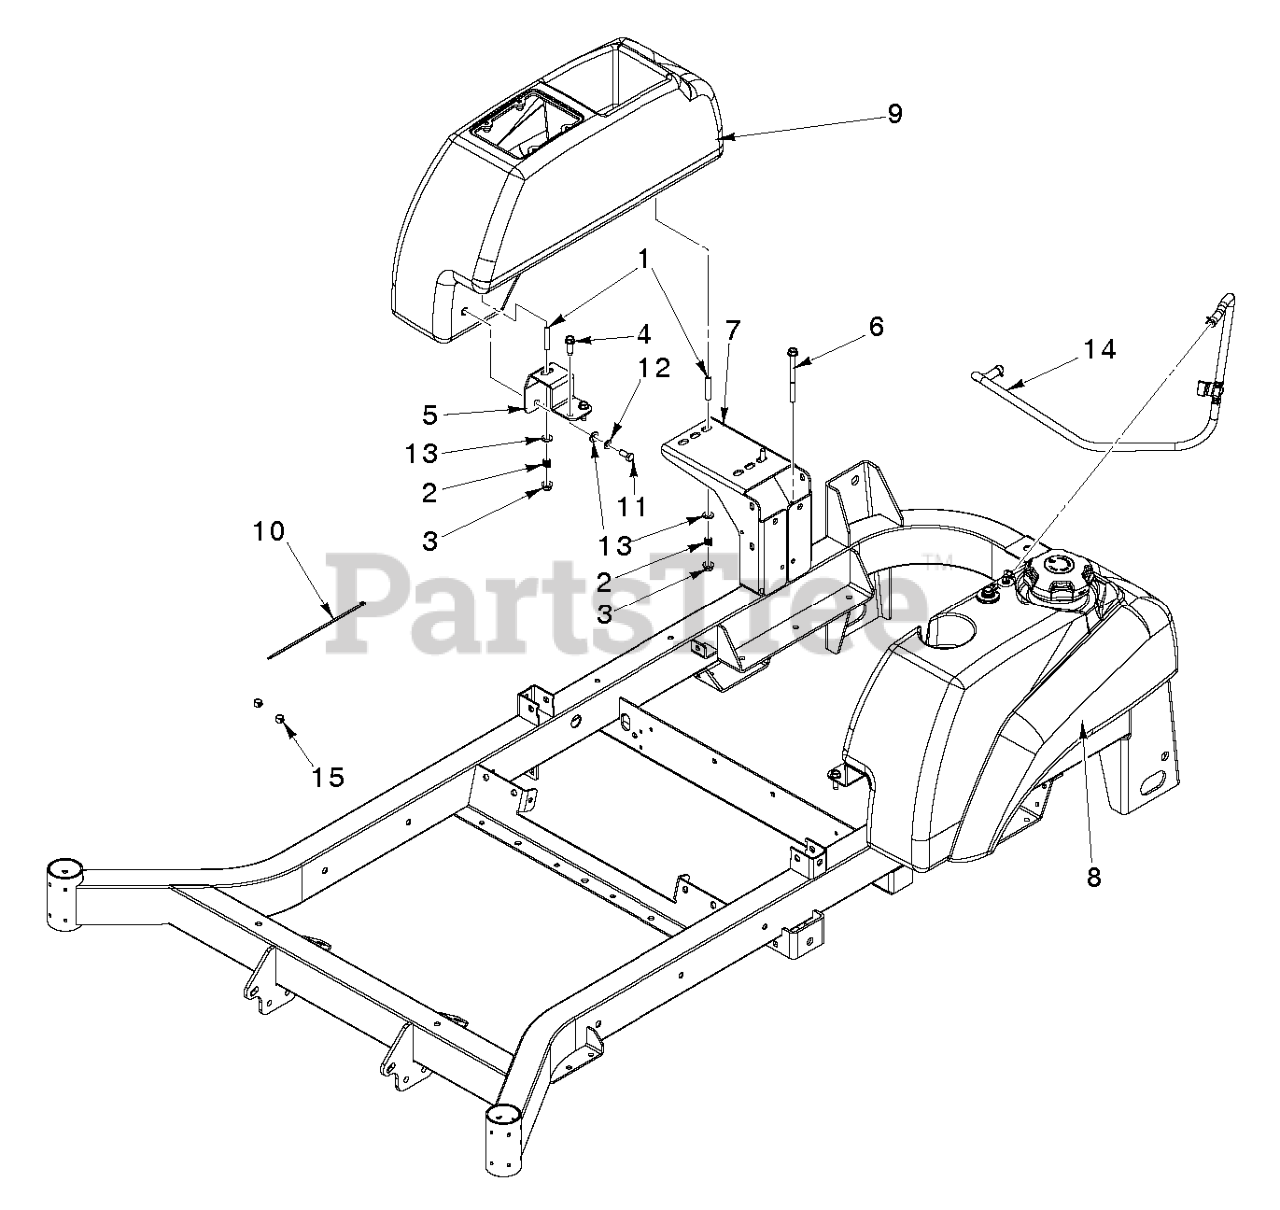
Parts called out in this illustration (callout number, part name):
1	STUD, 5/16C
3	NUT HEXAGON FLANGE 5/16-18 ST
4	SCREW HEX HEAD W/ WASHER 5/16-
5	SUPPORT.PNT.TANK.FRONT.STAMPED
6	BOLT.HEX.FLNG.5/16-18X3.75
7	MOUNT, TANK, ZT BLK
8	FUEL TANK ASSY LH MZ 2019
9	FENDER CONSOLE
10	TIE, PLASTIC
11	SCREW HEXAGON HEAD SCREW 5/16-
12	WASHER SPRING LOCK WASHER WITH
13	WASHER 11/32 X 11/16 X 14 GA T
14	HOSE.3/16".VAPOR.LINE.26"LGTH
15	TUBE.PURGE.FUEL.1875
